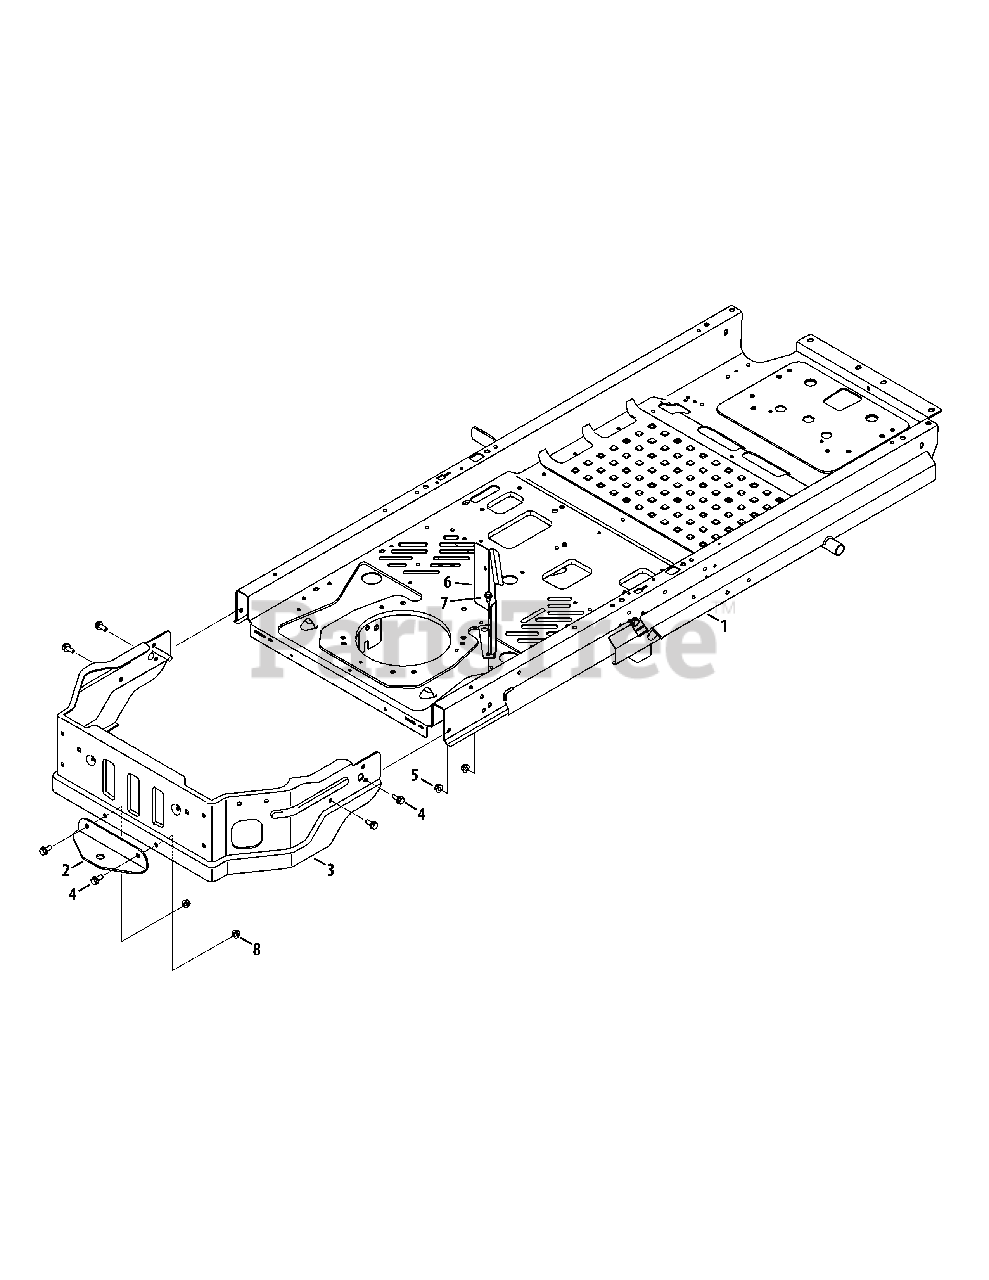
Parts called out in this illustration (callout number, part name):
1	Frame Assembly
4	Screw, 5/16-18, Hexflange
5	Flange Lock Nut, 5/16-18
6	Engine Heat Shield
7	Hex Washer Screw, 1/4-20 x .625
8	Flange Counter Lock Nut, 5/16-18
